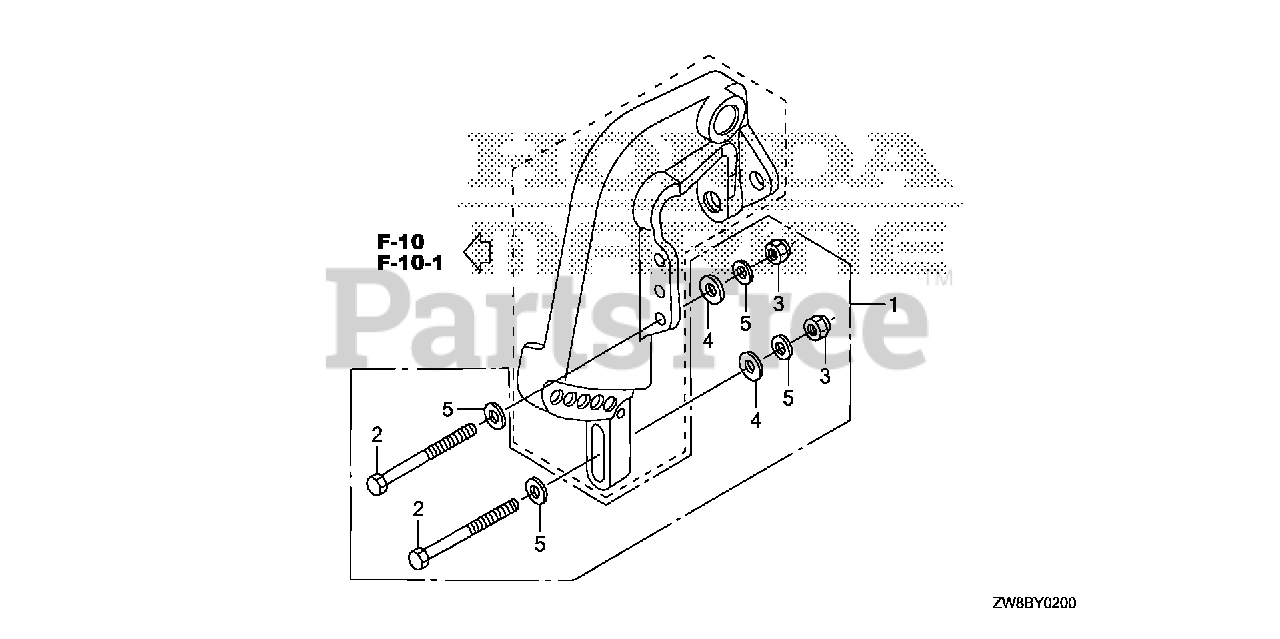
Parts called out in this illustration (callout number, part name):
1	INSTALLATION KIT, OUTBOARD
2	BOLT, HEX. (10X100)
3	NUT, SELF-LOCK (10MM)
4	WASHER, PLAIN (10MM)
5	WASHER, PLAIN (10MM)
